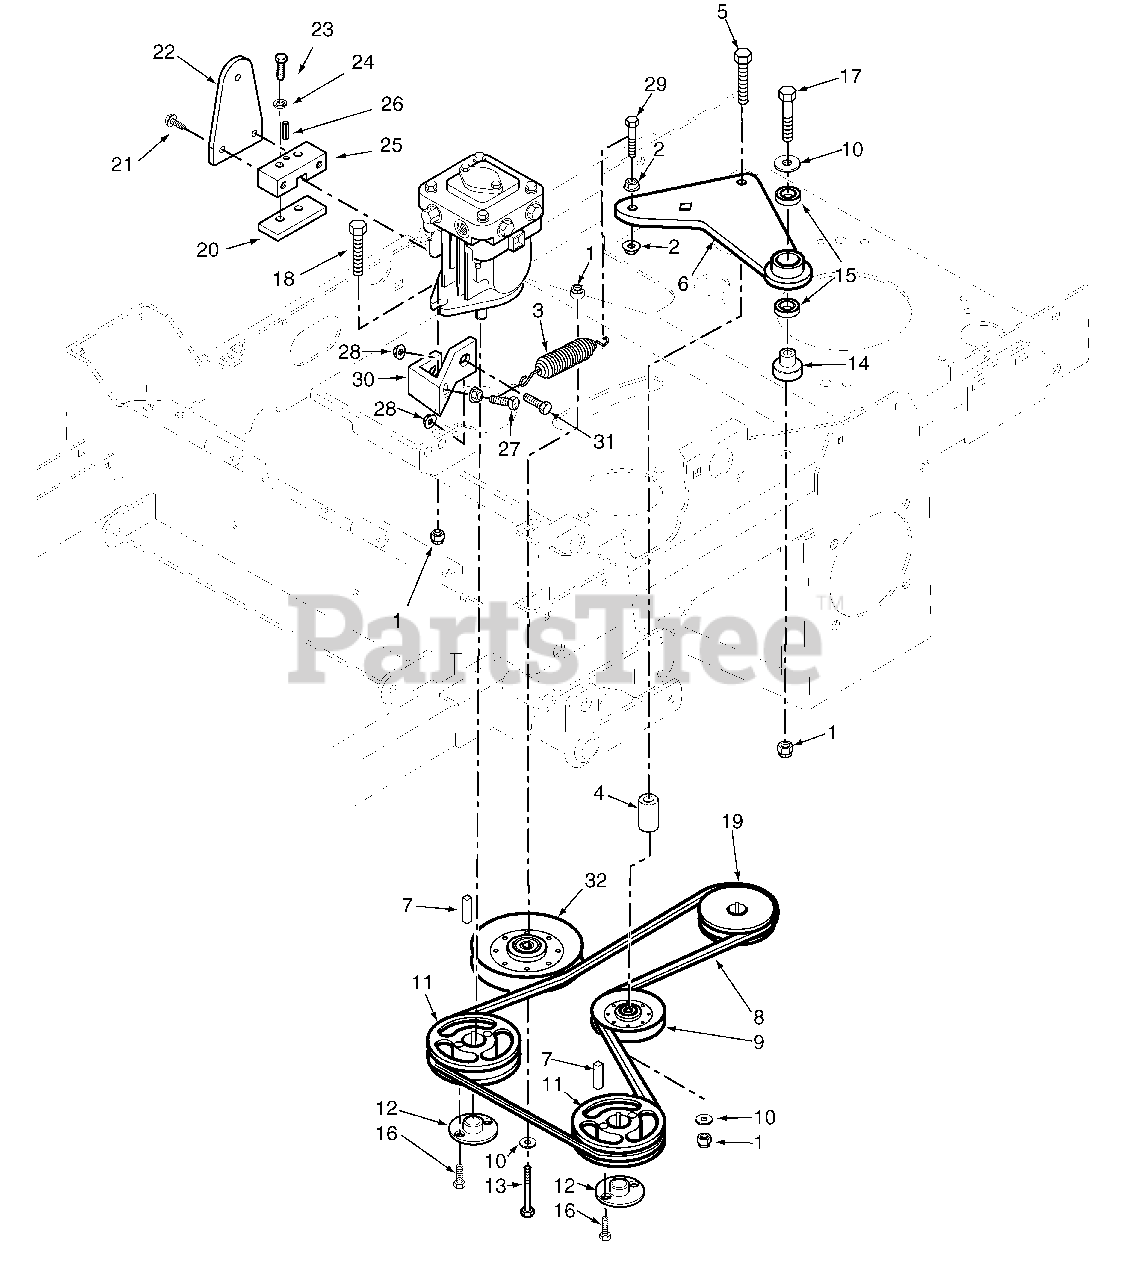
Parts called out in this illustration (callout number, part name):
1	Nut, Elastic Stop 3/8-16
2	Nut, Serrated Flange 3/8-16
3	Spring, Pump Idler
4	Spacer
5	Bolt, Hex Head 3/8-16 x 2-3/4"
6	Idler Arm Assy., Pump Drive
7	Key, 5 x 5 x 25mm
8	Belt, Transmission
9	Pulley, 3-1/2" Dia. Idler
10	Flatwasher, 3/8-.391 x .938 x .105
11	Pulley, 5.75 OD Taper Bore
12	Hub, Tapered, 15mm Bore
13	Bolt, 3/8-16 x 2"
14	Pivot, Idler
15	Bearing
16	Bolt, Hex Head 1/4-20 x 1" Grade 8
17	Bolt, Hex Head 3/8-16 x 2-1/2"
18	Bolt, Hex Head 3/8-16 x 1-1/2"
19	Pulley, 5.75 Dia. - 1.125" Bore
20	Clamp Plate
21	Hex Head Capscrew, 1/4-20 x 3/4"
22	Control Lever, Pump
23	Hex Head Capscrew, 1/4-20 x 3/4"
24	Lockwasher, 1/4"
25	Block, Pump Control
26	Roll Pin
27	Bolt, Hex Head 3/8-16 x 1-1/2" Grade 8
28	Nut, Serr. Flange 3/8-16
29	Bolt, Hex Head 3/8-16 x 1-1/2" Grade 8
30	Bracket
31	Bolt, Hex Head 3/8-16 x 1"
32	Pulley, 5" Dia. Idler
